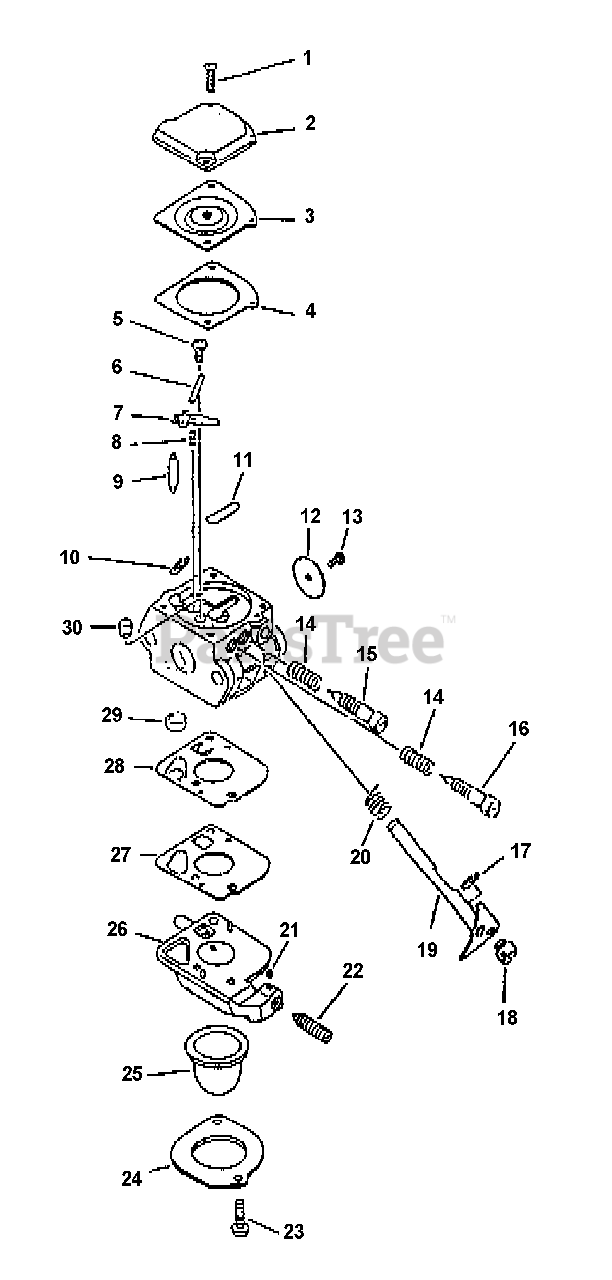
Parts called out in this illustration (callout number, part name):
2	COVER, DIAPHRAGM
3	DIAPHRAGM, METERING
4	GASKET, METERING
5	SCREW, METERING LEVER PIN
6	PIN, METERING LEVER
7	LEVER, METERING
8	SPRING, METERING LEVER
9	VALVE, THROTTLE
11	PLUG, WELCH
12	VALVE, THROTTLE
14	SPRING, NEEDLE
15	NEEDLE, LOW SPEED
16	NEEDLE, HIGH SPEED
19	SHAFT, THROTTLE
20	SPRING, THROTTLE RETURN
21	PIECE, FRICTION
22	SCREW, IDLE ADJUST
24	RETAINER
25	BULB, PURGE
26	BODY ASSY, PURGE
29	STRAINER
30	NOZZLE, CHECK VALVE
